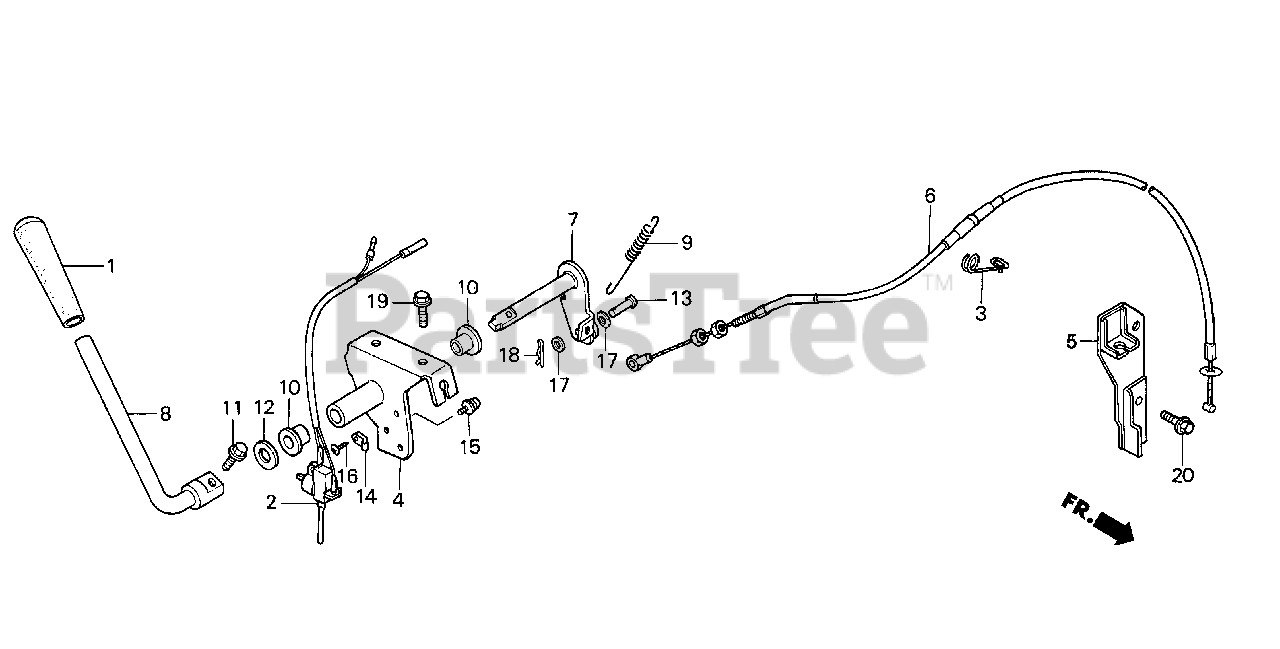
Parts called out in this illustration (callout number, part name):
1	GRIP, P.T.O. CLUTCH LEVER *Y121* (YELLOW)
2	SWITCH ASSY., FR. CLUTCH
3	GUIDE, CABLE
4	BRACKET, P.T.O. CLUTCH
5	HOLDER, P.T.O. CLUTCH WIRE
6	CABLE, P.T.O. CLUTCH
7	ARM, P.T.O. CLUTCH LEVER
8	LEVER, P.T.O. CLUTCH
9	SPRING, P.T.O. CLUTCH
10	BUSH, P.T.O. CLUTCH ARM
11	BOLT, FLANGE (6X12)
12	WASHER (14MM)
13	PIN, AUXILIARY CHANGE LEVER JOINT
14	CLIP, WIRE HARNESS (6.3MM)
15	SCREW-WASHER (4X12)
16	SCREW, TAPPING (4X10)
17	WASHER, PLAIN (6MM)
18	PIN, LOCK (6MM)
19	BOLT, FLANGE (8X16)
20	BOLT, FLANGE (8X20)
